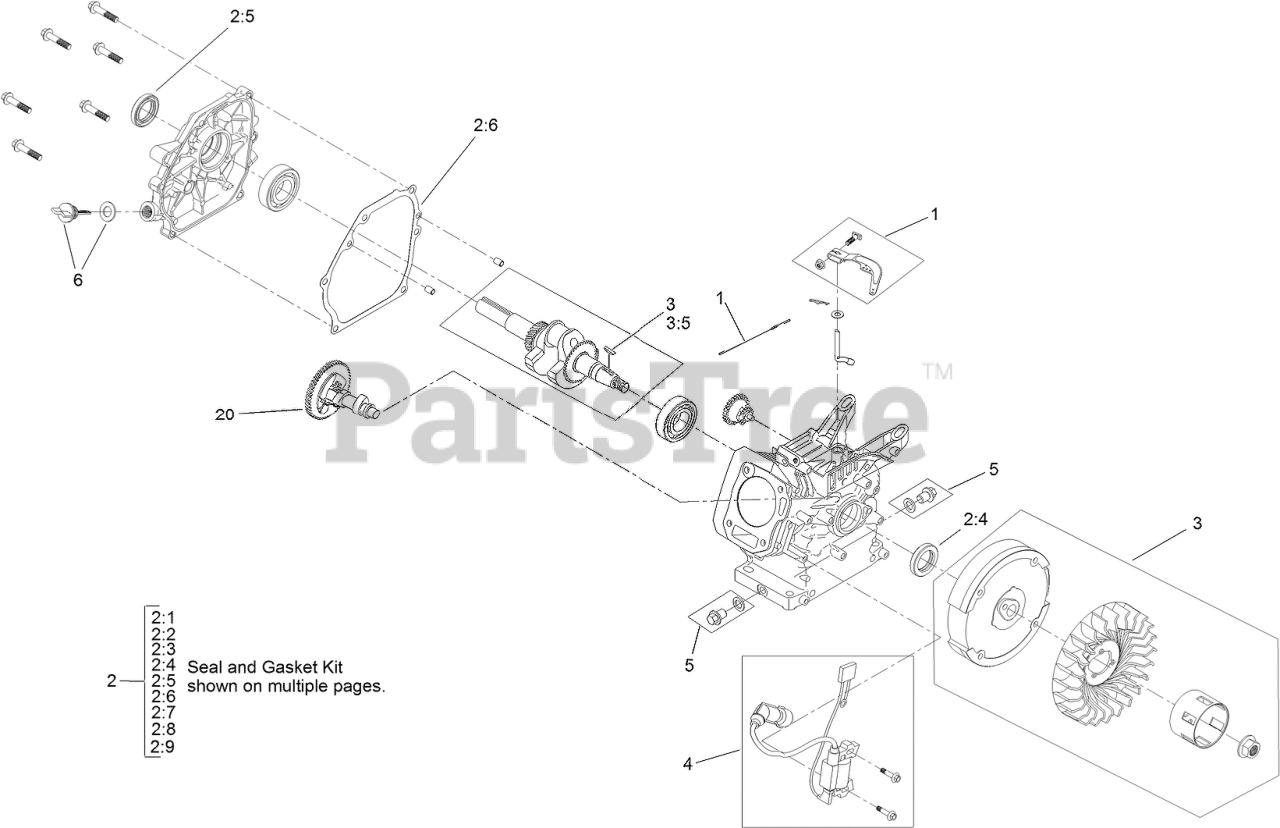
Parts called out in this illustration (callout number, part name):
1	GOVERNOR KIT
2	GASKET AND SEAL KIT
2:1	GASKET-COVER, VALVE
2:2	GASKET-EXHAUST
2:3	GASKET-HEAD, CYLINDER
2:4	SEAL-OIL
2:5	SEAL-OIL
2:6	GASKET-COVER, CRANKCASE
2:7	GASKET-CARBURETOR
2:8	GASKET-CARBURETOR
2:9	GASKET-CARBURETOR
3	RECOIL FLYWHEEL KIT
3:5	KEY-WOODRUFF
4	IGNITION KIT
5	DRAIN PLUG KIT
6	DIPSTICK AND O-RING KIT
20	CAMSHAFT
